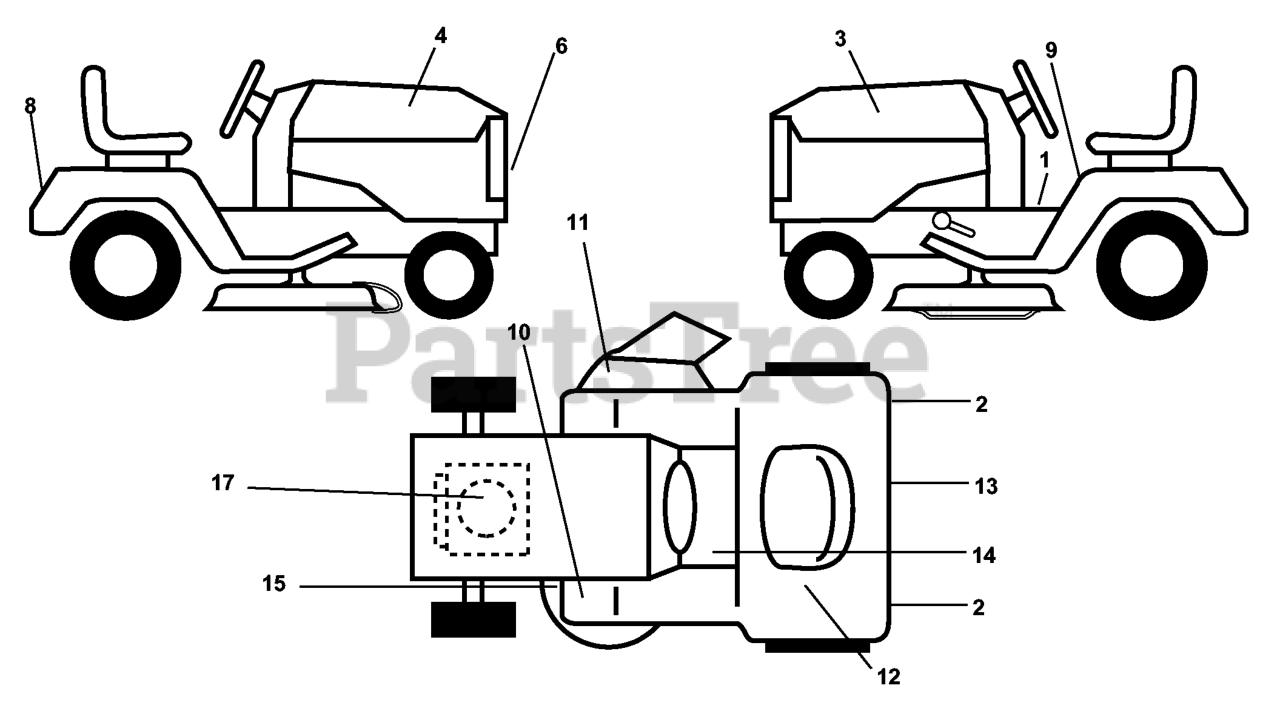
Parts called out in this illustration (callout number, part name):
1	DECAL DASH
2	TIRE HEAVY DUTY
3	DECAL, HOOD RH YTH150
4	DECAL HOOD RH
6	DECAL.GRILLE.HUSQ
8	DECAL FENDER HUSQ
9	DECAL CAUTION
11	DECAL WARNING (ENGLISH/FRENCH)
12	DECAL BTRY SYMBOLS
13	DECAL DRAWBAR CONTROL
15	DECAL V-BELT SCHEMATIC
17	DECAL ENGINE KOHLER 15HP
